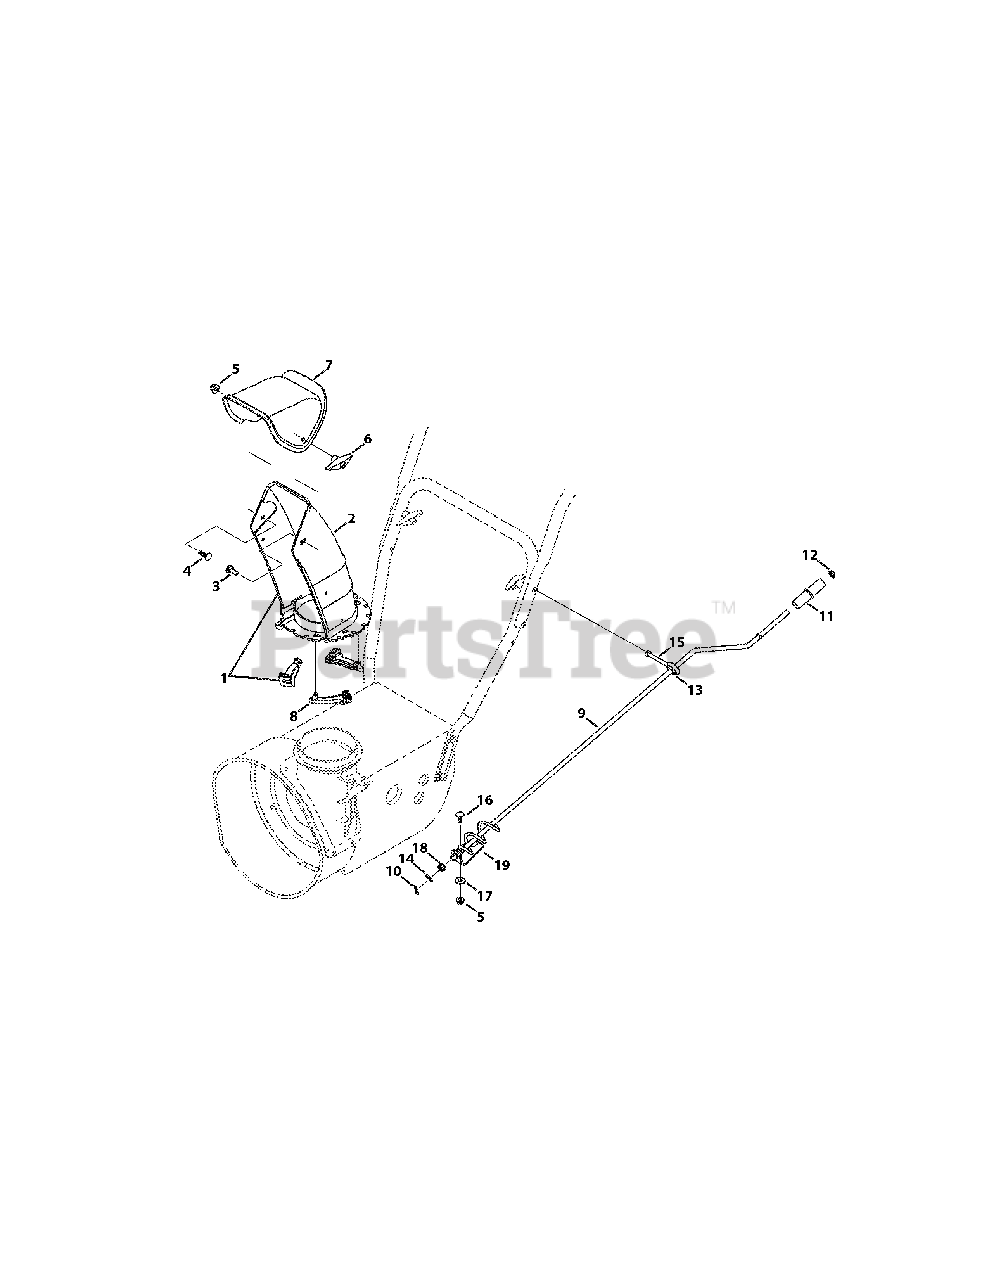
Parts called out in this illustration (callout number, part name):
1	Lower Chute Assembly
2	Lower Chute
3	Carriage Bolt, 5/16-18 x 1.00
4	Carriage Bolt, 5/16-18 x .750
5	Flange Lock Nut, 5/16-18
6	Wing Knob
7	Upper Chute
8	Flange Keeper
10	Cotter Pin, .072 x 1.13
11	Crank Knob
12	Push Cap, 3/8
13	Rubber Grommet
14	Flat Washer, .375 x .738 x .063
16	Carriage Screw, 5/16-18 x 1.00
17	Flat Washer, .349 x .879 x .063
18	Plastic Bushing, .380 ID
19	Chute Crank Bracket
